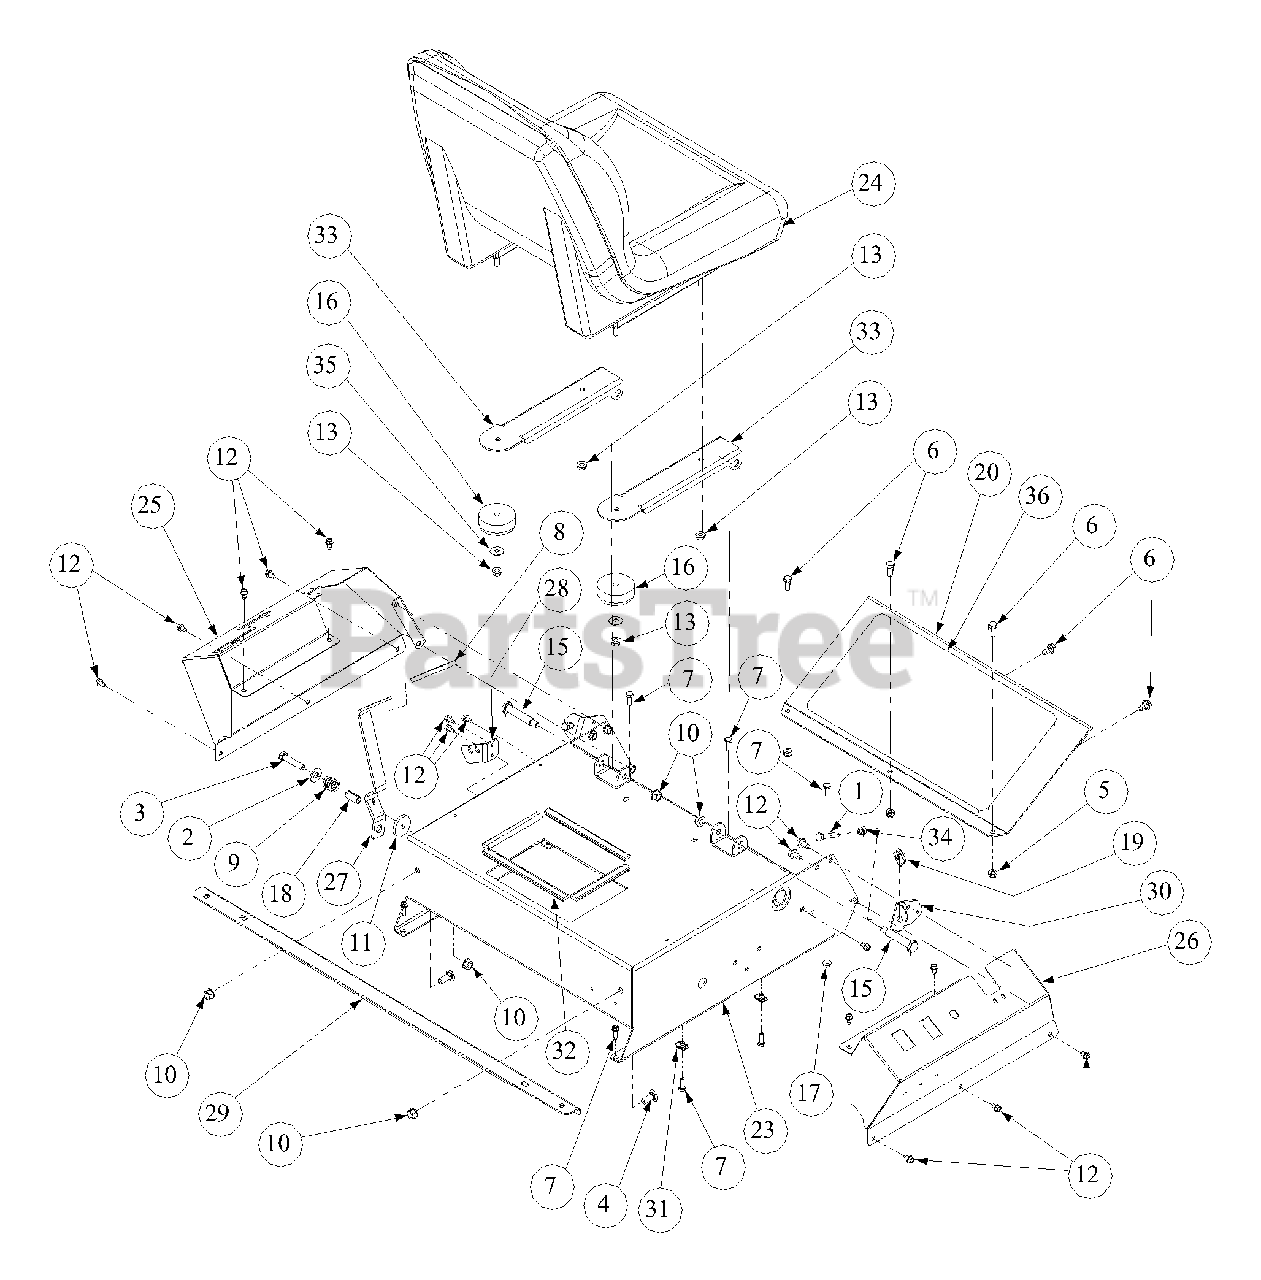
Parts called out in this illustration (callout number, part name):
1	Hex Cap Screw, 5/16-18 x 1-1/2
2	Idler Washer
3	Capscrew, 3/8-16 x 1-3/4
4	Carriage Bolt, 3/8-16
5	Nylock Nut, 5/16-18
6	Self Tapping Screw, 5/16-18 x 3/4
7	Self Tapping Screw, 1/4-20 x 1.2
8	Parking Brake Grip
9	Spring, .80 OD x 1 Lg
10	Hex Nut, 3/8-16 Flange Lock
11	Flat Washer, 1.25 x .411 x .100
12	Screw, 1/4-20 x 1/2
13	Hex Nut, 5/16-18 Flange Lock
15	Shoulder Screw, 3/8-16, .5 x 2.345
16	Groment, 2.5 OD x 1.0 Lg
17	Hex Nut, 1/4-20 Flange Lock
18	Spacer, .375 x .50 x 1.02
19	U-Nut, 5/16-18
20	Foot Rest Bracket
23	Control Housing Weldment
24	Seat Adjust
25	Left Hand Control Console
26	Right Hand Control Console
27	Parking Brake Lever
28	Brake Cable Bracket
29	Front Tank Mounting Bracket
30	Lapbar Stop Bracket
31	U-Nut, 1/4-20
32	Battery Edge Trim
33	Seat Mounting Bracket
34	Hex Nut, 5/16-18
35	Washer, .325 x .930 x .045
36	Abrasive Foot Pad
